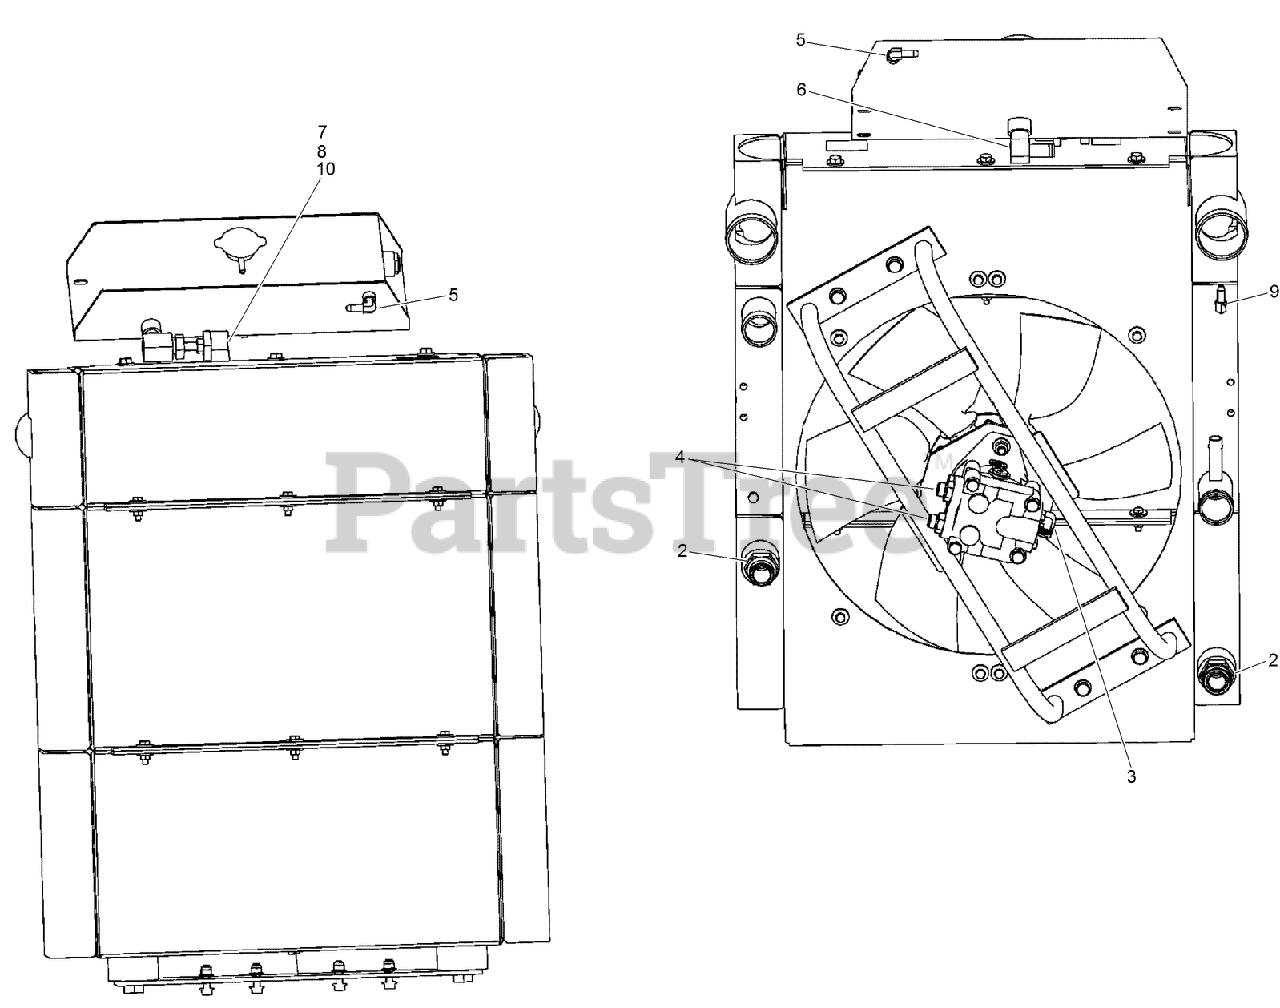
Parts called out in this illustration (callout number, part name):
2	CONNECTION - Straight, -16 ORFS / -20 ORB
3	CONNECTION - 90 Deg, -8 ORFS / -8 ORB
4	CONNECTION - Straight, -8 ORFS / -10 ORB
5	ELBOW - 90 Hose Stem, 3/8 ID x 174 NPTF
6	STEM-90, BEAD HOSE
7	ELBOW - 90, 1/2 NPTF Male/Female, MI Blk
8	BUSHING - Reducer, Internal/External, NPT
9	STEM - Straight Hose Barb, 3/8ID X1/4N
10	SENSOR-LEVEL, COOLANT
